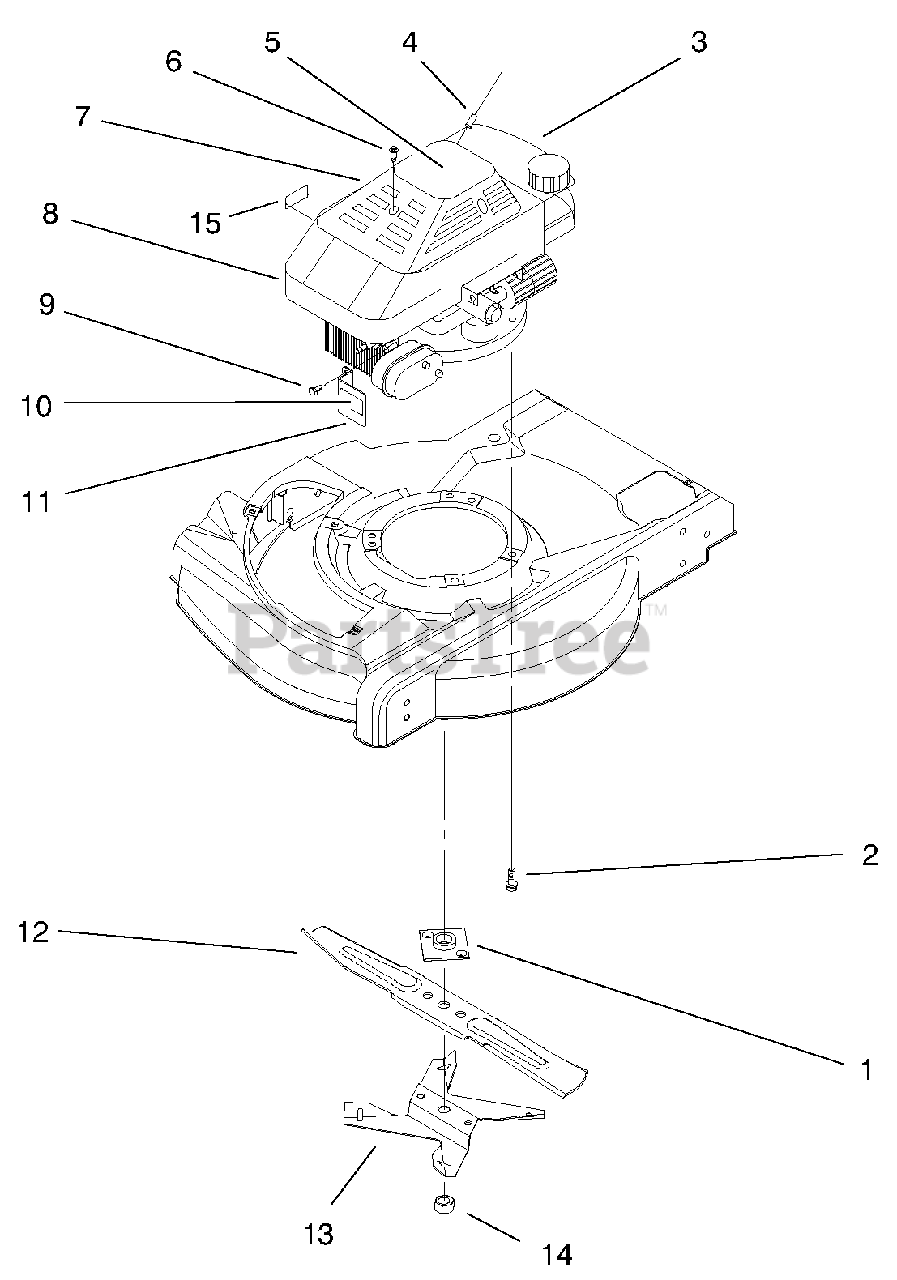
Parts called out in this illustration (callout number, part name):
1	ASM-Plate & Collar
2	Screw-Engine Mount
3	ASM-Engine
4	Rope-Stop
5	Decal-Shroud
6	Screw-Recoil Cover
7	Cover-Starter
8	Shroud-Engine
10	Decal-Hot Surface
11	Guard-Muffler
12	Blade-21" Whirl
13	Fan-Mulching
14	Nut-Blade
15	Decal-Oil Instruction
